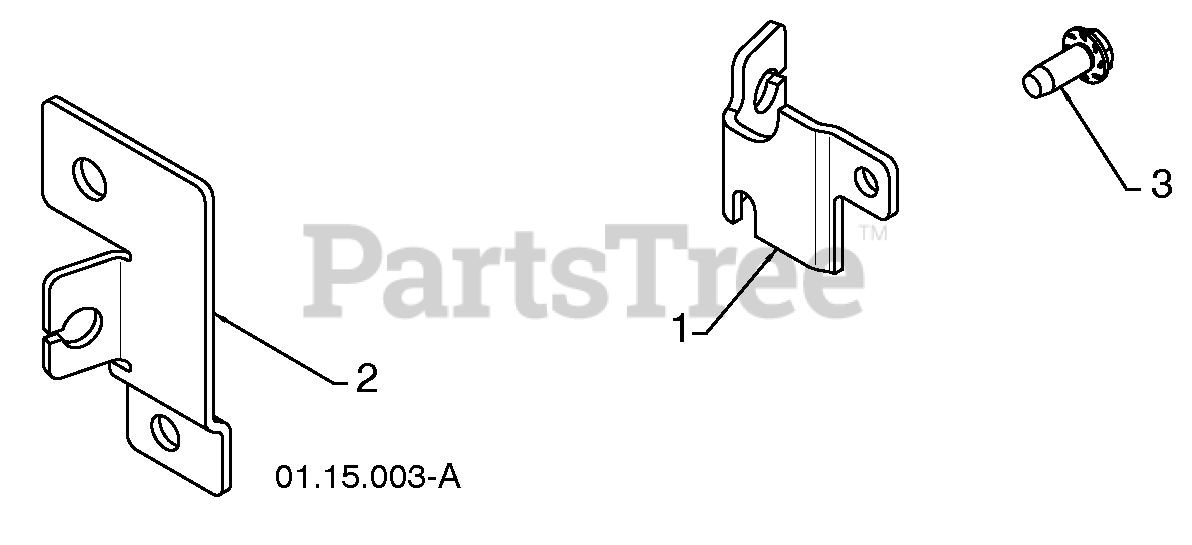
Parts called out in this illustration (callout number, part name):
1	CABLE BRACKET LH
2	CABLE BRACKET RH
3	SCREW 1/4-20 X .625
